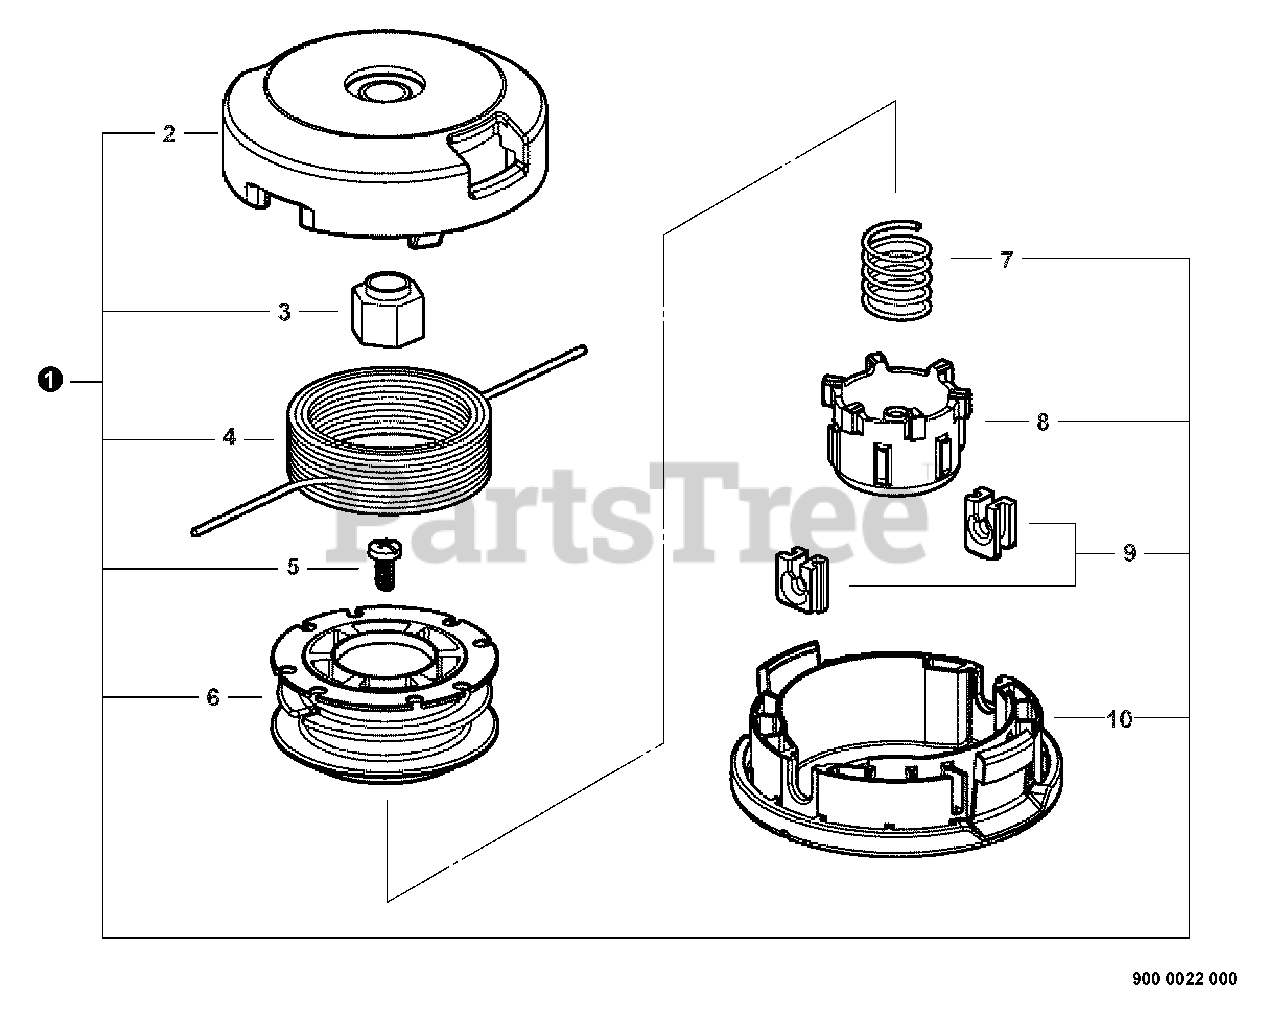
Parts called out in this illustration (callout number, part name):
1	G137 TRIMMER HEAD
3	BUSHING
4	LINE, TRIMMER
8	CAM - INNER
10	HOUSING
